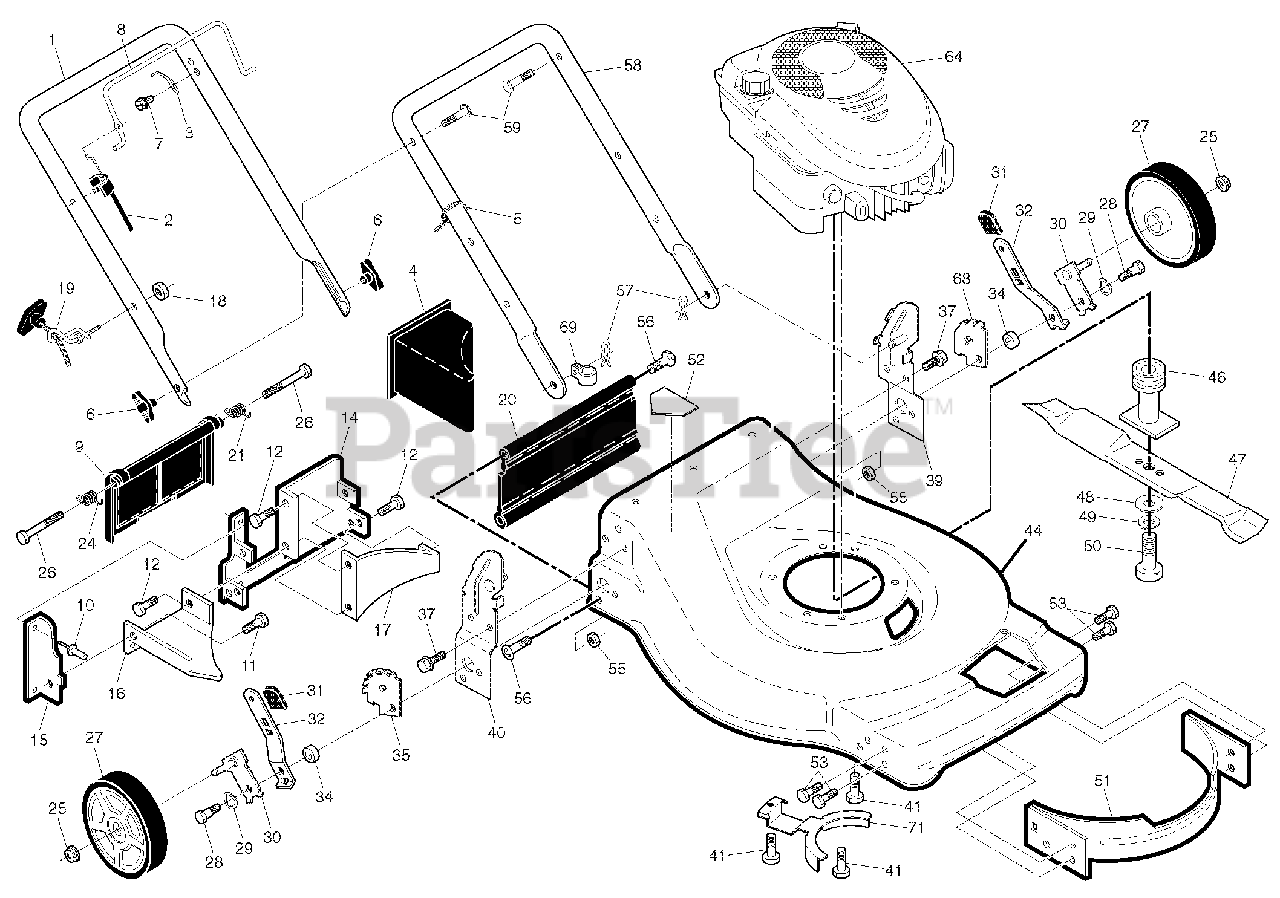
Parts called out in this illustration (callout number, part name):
1	Upper Handle
2	Engine Zone Control Cable
3	Bracket, Upstop
4	MULCH PLUG
5	Wire Tie
6	Handle Knob
7	Hex Washer Head Screw
8	CONTROL BAR
9	Rear Door Assembly
10	Pop Rivet
11	Screw, Self-Tapping
12	SCREW, SEMS, HEX HEAD 1/4-20 X
14	Back Plate
15	Side Baffle
16	Discharge Baffle
17	Rear Baffle
18	Nut, Hex
19	Rope Guide
20	REAR SKIRT
21	Spring, Rear Door, LH
24	Spring, Rear Door, RH
25	Nut, Hex
26	Bolt, Rear Door
27	REAR WHEEL
28	Bolt, Shoulder 3/8-16 x 1
29	Washer, Curved, Cylindrical
30	AXLE ARM ASSEMBLY
31	Selector Knob
32	Selector Spring, Front
35	WHEEL ADJUSTING BRKT RH
37	Screw, Sems, Thread Cutting 5/
39	HANDLE BRACKET ASSEMBLY LH
40	HANDLE BRACKET ASSEMBLY RH
41	Screw, Hex Head, Threaded, Rol
44	DECK, WALK BEHIND
46	PULLEY, BLADE ADAPTER
48	Hardened Washer
49	Helical Lockwasher
50	Screw, Hex Head, Grade 8 3/8-2
51	Kit, Front Baffle
52	Danger Decal
53	SCREW.HEX.WASHEAD.1/4-20 X 3/8
55	NUT.CENTERLOCK.3/8-16 UNC.
56	Hinge Screw
57	Hairpin Cotter
58	Lower Handle
59	Handle Bolt
64	Engine, Briggs & Stratton, Model Number 126L02- 1459-F1 (For engine service and replacement parts,
68	WHEEL ADJUSTING BRKT LH
69	Clip, Cable
71	BELT KEEPER
